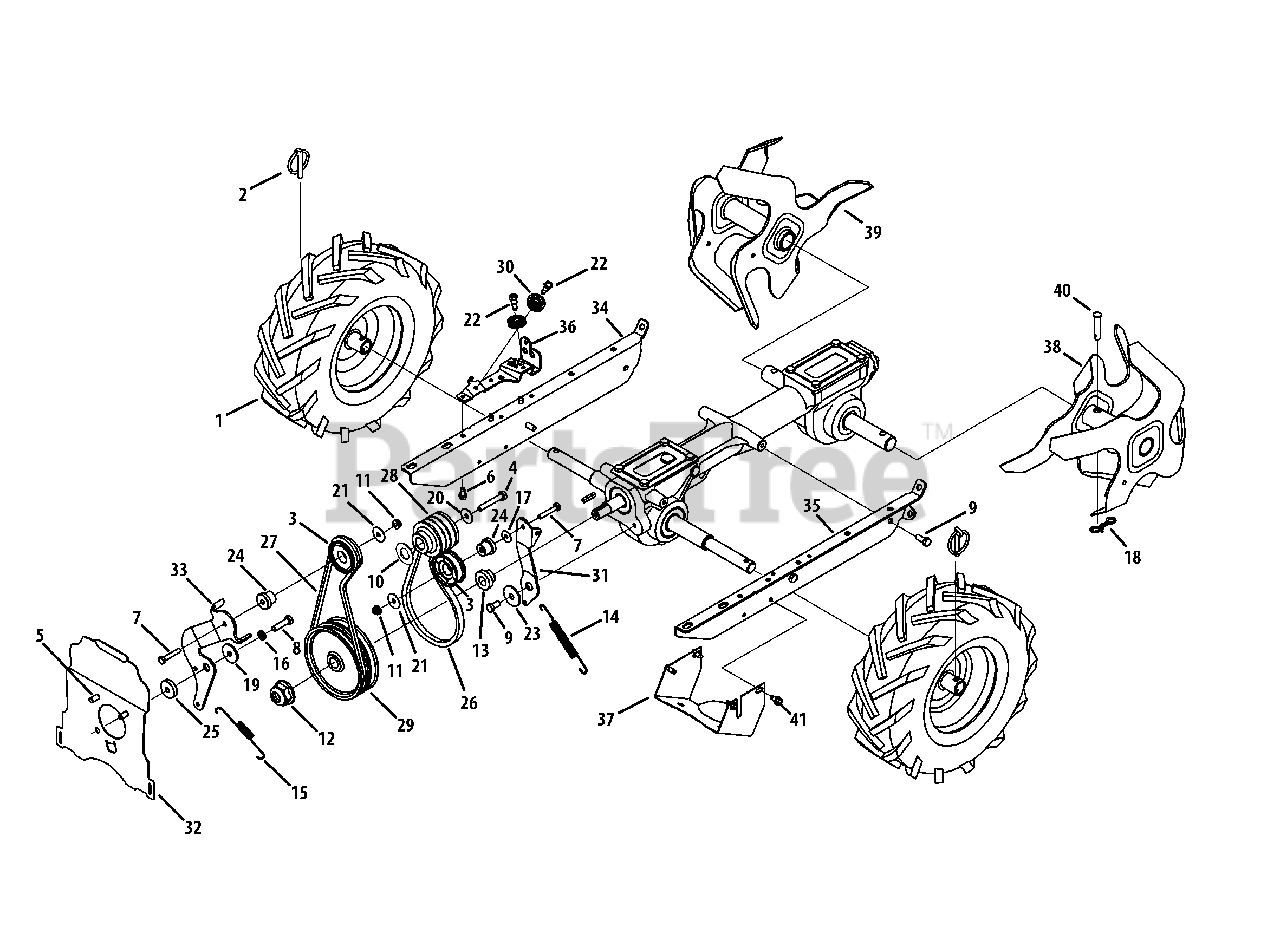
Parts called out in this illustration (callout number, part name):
1	Complete Whl. Ass., 13 x 5 x 6
2	Klik Pin
3	Idler Pulley Assembly
4	Hex Head Screw, 3/8-24 x 2.25
5	Hex Head Screw, 5/16-24 x .625
6	Self Tapping Screw, 1/4-20 x .500
7	Hex Head Screw, 1/4-20 x 1.50
8	Hex Head Screw, 5/16-18 x 1.25
9	Hex Head Screw, 5/16-18 x .75, Patch
10	Washer, Flat, .760 x 1.50 x .120
11	Nylon Hex Lock Nut, 1/4-20
12	Nut, 9/16-18, Flange Lock
13	Hub, 5/8 Spline
14	Extension Spring, .480 OD X 5.00 LG
15	Extension Spring, LT5 PTO
16	Lock Washer, 5/16
17	Washer, .28 x .74 x .063
18	Cotter Pin, Bow Tie
19	Flat Washer, .330 X 1.25 X .120
20	Bell Washer, .396 x 1.140 x .095
21	Flat Washer, .265 x 1.0 x .030
22	Shoulder Screw, .342 x .335 1/4-28
23	Pivot Idler Spacer
24	Shoulder Spacer, .260 x .785 x .538
25	Pivot Idler Spacer
26	V-Belt, 4L x 25.375 Long
27	V-Belt, 3L x 29.125 Long
28	Engine Pulley
29	Transmission Pulley
30	Cable Roller
31	Idler Bracket, Forward
32	Cover Plate
33	Idler Bracket, Reverse
34	Mounting Frame, RH
35	Mounting Frame, LH
36	Pulley Bracket
37	Pulley Shield
38	Tine Assembly, LH
39	Tine Assembly, RH
40	Clevis Pin, .375 x 1.75
41	Self Tapping Screw, 1/4-14 x .625
